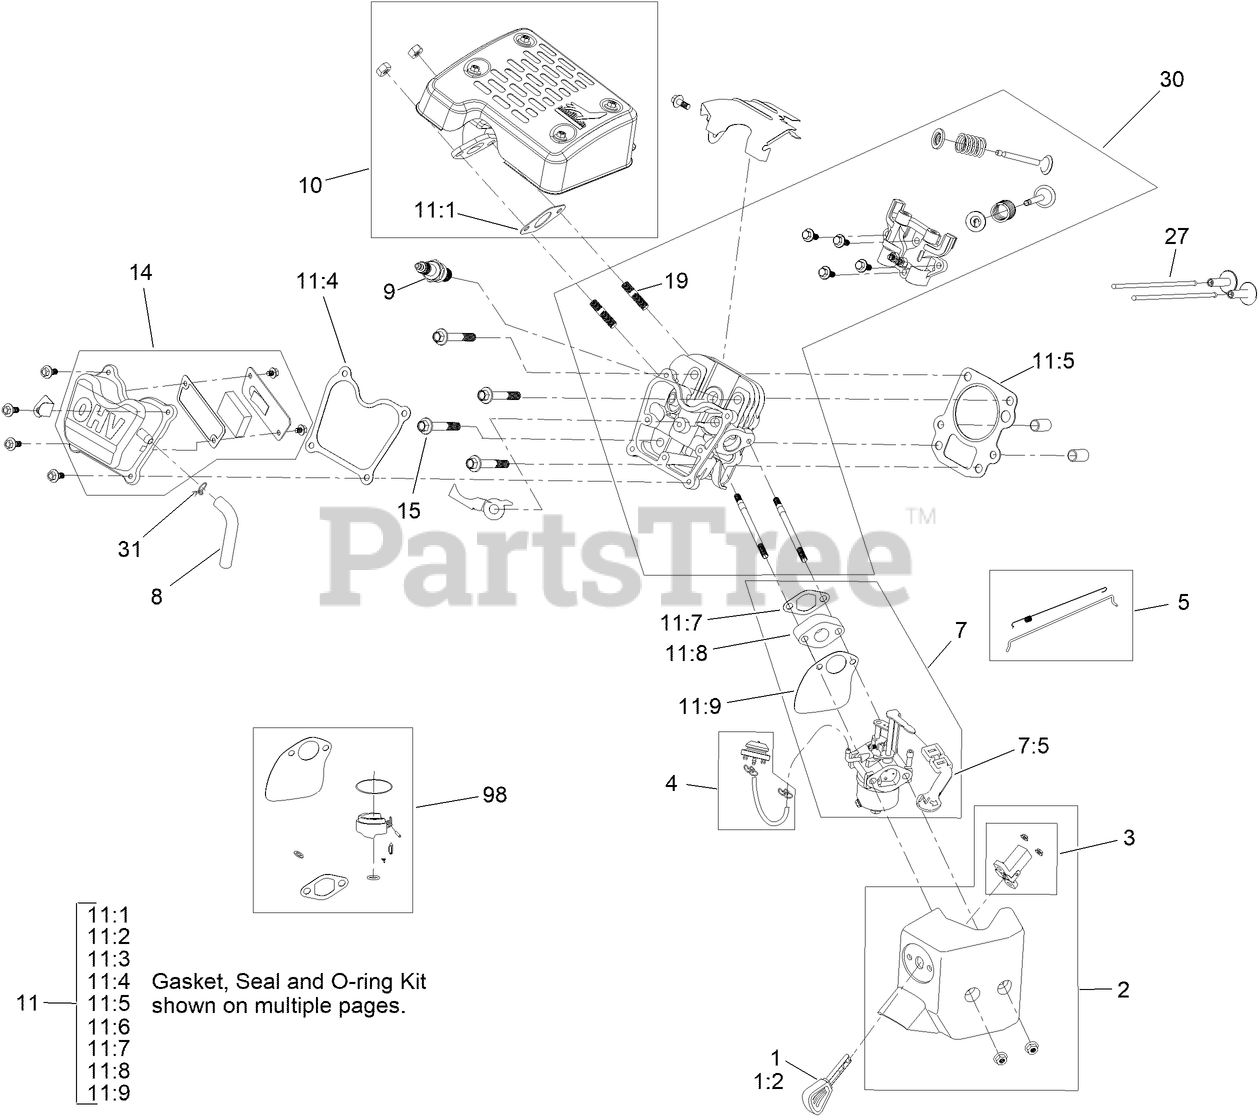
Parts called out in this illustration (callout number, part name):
1	KEY AND LANYARD KIT
2	HEATER BOX KIT
3	SWITCH KIT
4	PRIMER BULB KIT
5	GOVERNOR KIT
7	COMPLETE CARB SERVICE KIT
7:5	LEVER-CHOKE
8	TUBE-BREATHER
9	SPARK PLUG
10	MUFFLER KIT
11	GASKET, SEAL, AND O-RING KIT
11:1	GASKET-EXHAUST
11:2	SEAL-OIL
11:3	SEAL-OIL
11:4	GASKET-COVER, VALVE
11:5	GASKET-HEAD, CYLINDER
11:6	GASKET-COVER, CRANKCASE
11:7	GASKET-INSULATOR
11:8	INSULATOR-CARBURETOR
11:9	GASKET-CARBURETOR
14	VALVE COVER ASM
15	SCREW-HHF
19	STUD-EXHAUST
27	ROD-PUSH
30	COMPLETE HEAD ASM
31	CLAMP-HOSE
98	CARBURETOR REPAIR KIT
